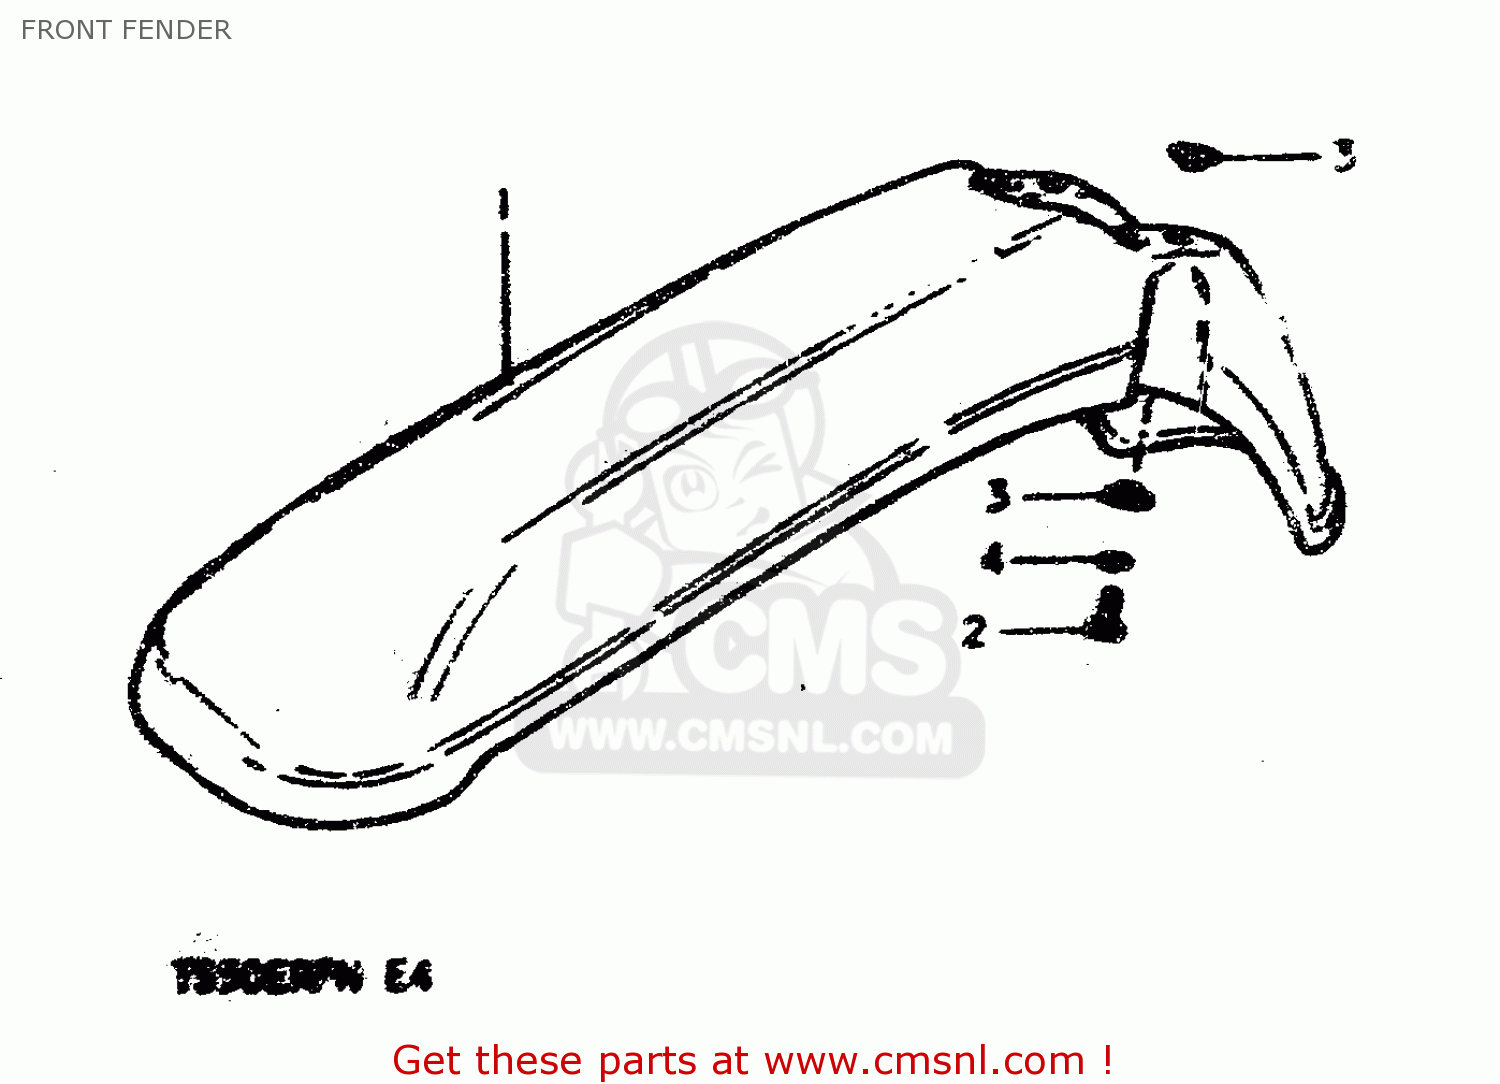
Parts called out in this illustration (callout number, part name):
1	FENDER, FRONT
2	BOLT, UPPER
3	SPACER
4	LOCK WASHER
